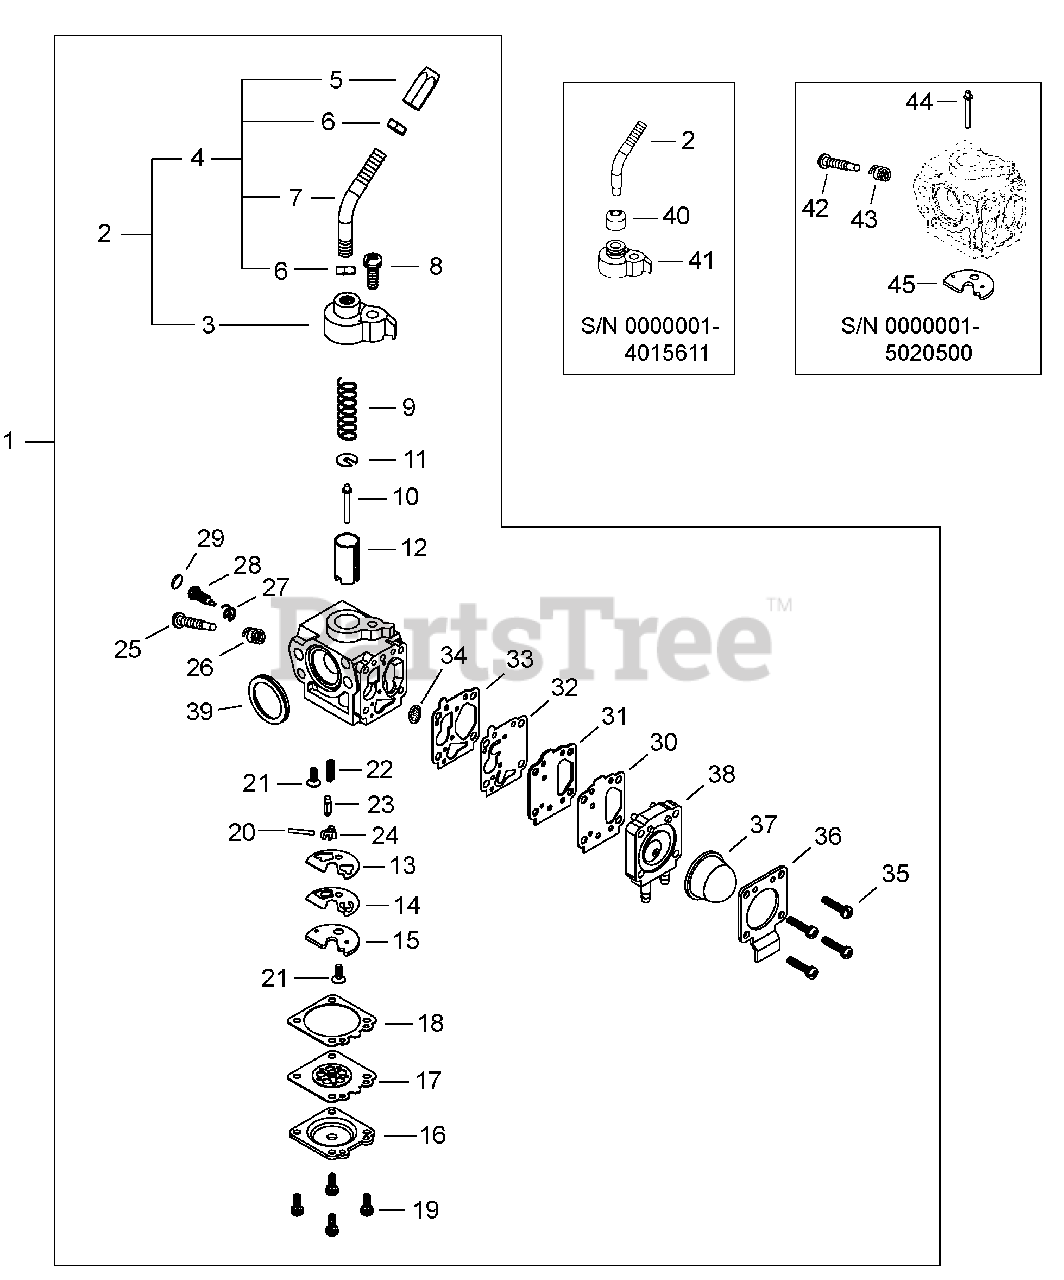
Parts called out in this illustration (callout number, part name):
1	CARBURETOR
2	ADJUSTER ASSY, CABLE
3	CAP, CARBURETOR
4	ELBOW ASSY
5	ADJUSTER, CABLE
6	NUT, LOCK
7	ELBOW
8	SCREW M5×15
9	SPRING, THROTTLE
10	NEEDLE, JET
11	WASHER, SPRING SUPPORT
12	VALVE, THROTTLE
13	GASKET
14	VALVE, CHECK
15	PLATE
16	COVER, DIAPHRAGM
17	DIAPHRAGM, METERING
18	GASKET, METERING DIAPHRAGM
19	SCREW M3×8
20	PIN, METERING LEVER
21	SCREW M3×8
22	SPRING
23	VALVE, INLET NEEDLE
24	LEVER, METERING
25	SCREW, IDLE ADJUST
28	SCREW, MAIN ADJUST
29	PLATE
30	GASKET, FUEL PUMP
31	PLATE, PUMP
32	DIAPHRAGM, FUEL PUMP
33	GASKET, PUMP
34	SCREEN, FUEL INLET
35	SCREW M3×14
36	COVER, PUMP
37	BULB, PURGE
38	COVER ASSY, PUMP
39	RING, PACKING
40	CAP, DUST
41	CAP, CARBURETOR
42	SCREW, IDLE ADJUST
43	SPRING
44	NEEDLE, JET
45	PLATE
